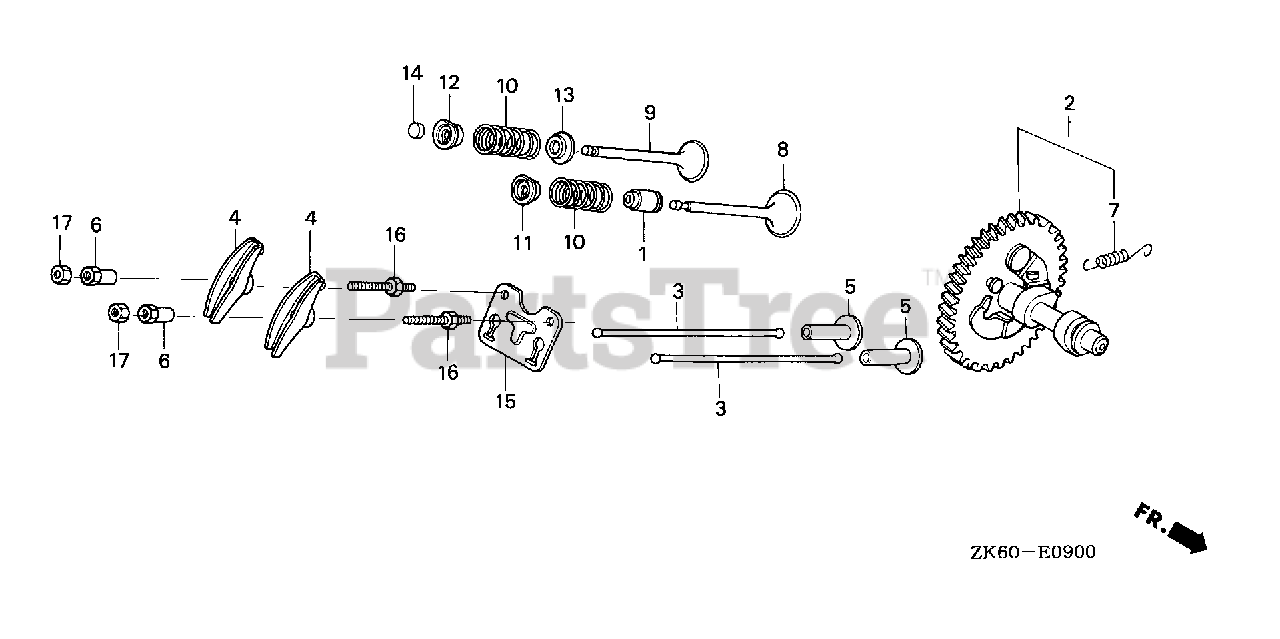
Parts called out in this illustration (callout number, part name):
1	SEAL, VALVE STEM
2	CAMSHAFT ASSY.
4	ARM, VALVE ROCKER
5	LIFTER, VALVE
6	PIVOT, ROCKER ARM
7	SPRING, WEIGHT RETURN
8	VALVE, IN.
9	VALVE, EX.
10	SPRING, VALVE
11	RETAINER, IN. VALVE SPRING
12	RETAINER, EX. VALVE SPRING
13	SEAT, VALVE SPRING
14	ROTATOR, VALVE
15	GUIDE, PUSH ROD
16	BOLT, PIVOT (8MM)
17	NUT, PIVOT ADJUSTING
